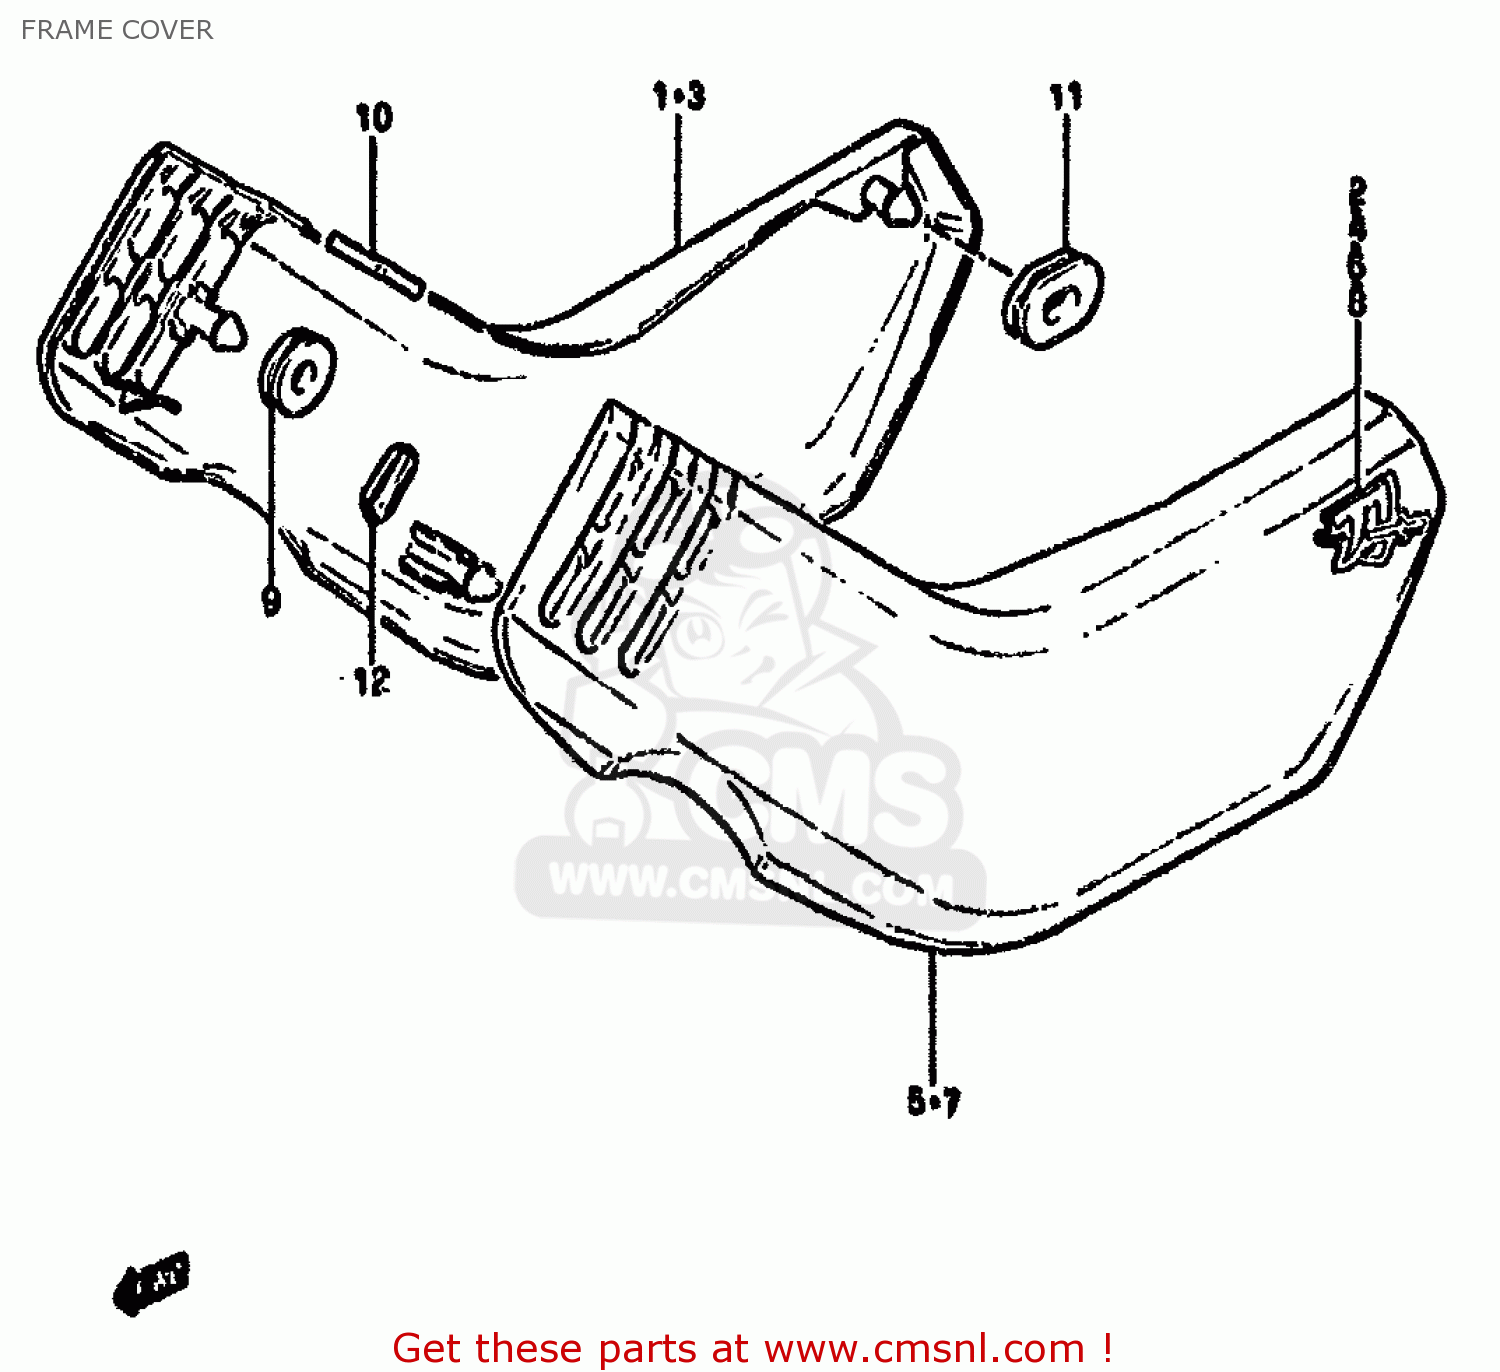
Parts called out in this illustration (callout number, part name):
1	COVER,FRAME,RIGHT
2	EMBLEM
3	COVER,FRAME,RIGHT
4	EMBLEM,FRAME COVER
5	COVER,FRAME,LEFT
6	EMBLEM
7	COVER,FRAME,LEFT
8	EMBLEM,FRAME COVER
9	CUSHION
10	CUSHION
11	CUSHION
12	EMBLEM,FRAME COVER
